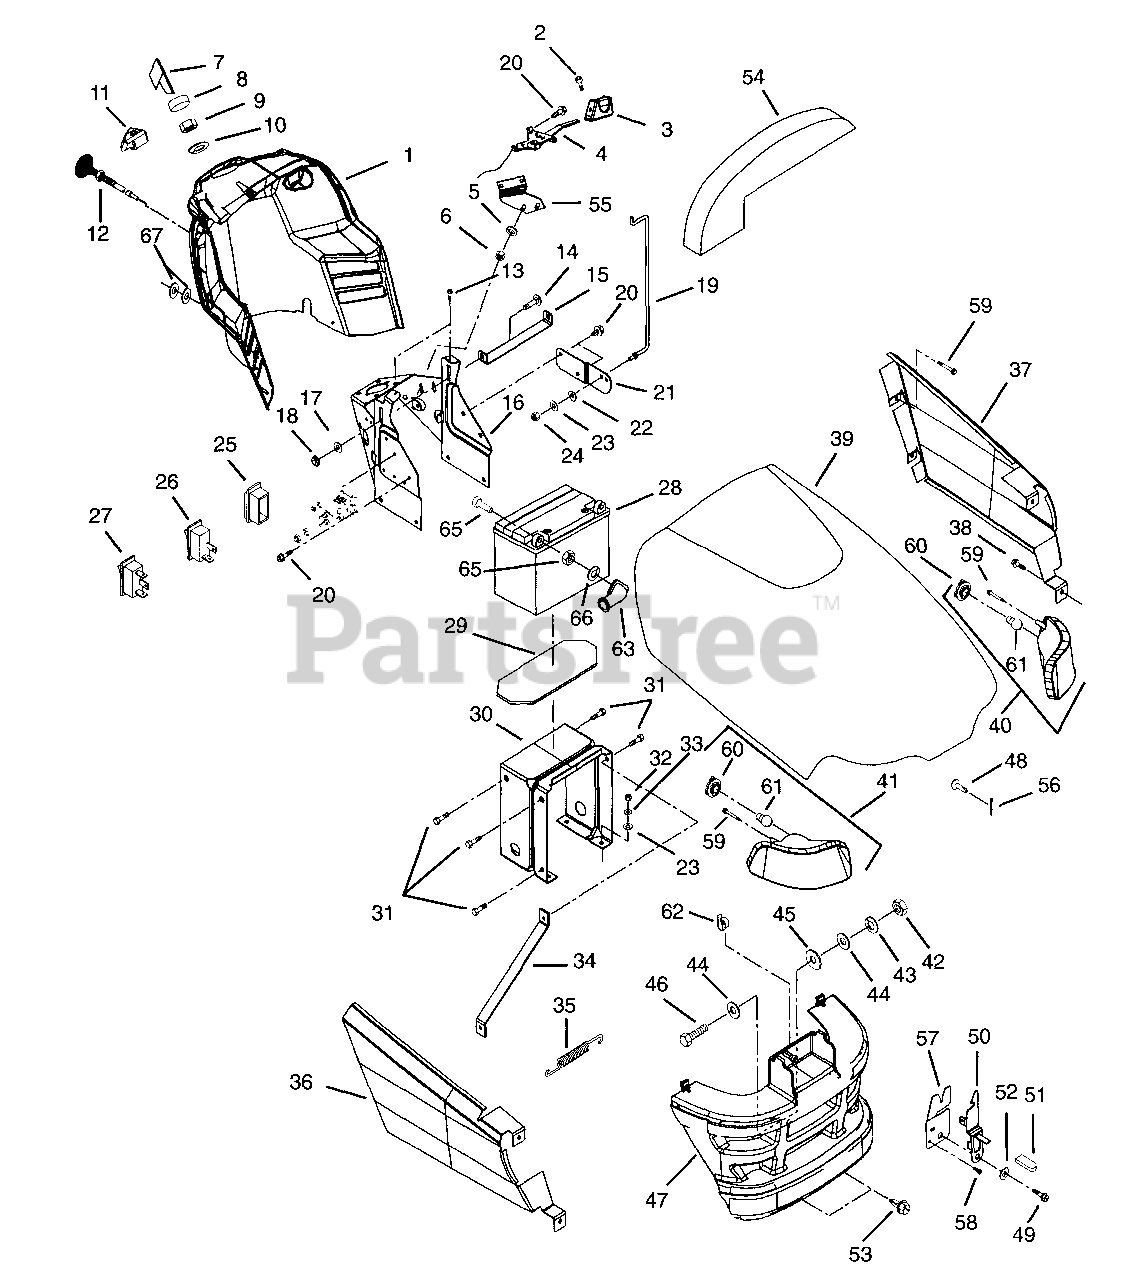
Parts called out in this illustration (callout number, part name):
1	Dash
2	Screw-Set 10-24 x .38
3	Knob-Throttle
4	Throttle Control-Tec/B & S
5	Washer-Flat-Steel .323 x .625 x .062
6	Nut-Locking-Center .250-20
7	Key-w/Cap
8	Cap-Ignition Switch
9	Nut-Panel .562-24
10	Washer-Lock Internal .563 x .040
11	PTO Knob/Switch Assembly
12	Choke Cable
13	Screw-Tapping 10-24 x .484
14	Bolt-Round Head Square Neck .31-18 x .75
15	Holddown-Battery
16	Support-Dash-Top
17	Washer-Flat-Steel .323 x .625 x .062
18	Nut-Locking-Nylon .312-18
19	Rod-Hood Prop
20	Screw-Tapping .250-20 x .37
21	Mount-Prop Rod
22	Wave Washer
23	Washer-Flat-Steel .312 x .734 x .065
24	Nut-Locking-Center .250-20
26	Switch-Light
27	Switch-Cruise
28	Battery w/Tube
29	Rubber Pad
30	Support-Dash-Base
31	Screw-Tapping .312-18 x .50
32	Nut-Hex .312-18
33	Washer-Lock .312 x .097
35	Spring-Tension .035 x .45 x 2.75
36	Side Panel-Right Hand
37	Side Panel-Left Hand
38	Screw-Tapping 12-16 x .500
39	Hood with Decals
40	Headlight-Left Hand
41	Headlight-Right Hand
42	Nut-Hex .312-18
43	Washer-Lock .312 x .097
44	Washer .328 x 1.0 x .094
45	Washer-Flat-Nylon .375 x 1.000 x .062
46	Bolt-Hex .31-18 x 1.00 Grade 5
47	Grill
48	Clevis Pin .243/.248 x 1 1/2
49	Screw-Tapping 12-24 x .50
50	Hood Latch
51	Grip .062 x .375 x .750
52	Washer-Flat-Steel .281 x 1.250 x .048
53	Screw-Tapping .312-18 x .50
56	Pin-Cotter .09 x .75
57	Locator-Hood
58	Screw-Tapping 10-12 x .50
59	Screw-Tapping 10-24 x .75
60	Lamp Socket
61	Headlight Bulb
62	Clip-Harness
63	Insulator
64	Bolt-Hex .25 - 20 x .75 Grade 5
65	Washer-Locking .250 x .077 Heavy
66	Nut-Hex .25-20
67	Washer-Flat-Steel .219 x .500 x .049
